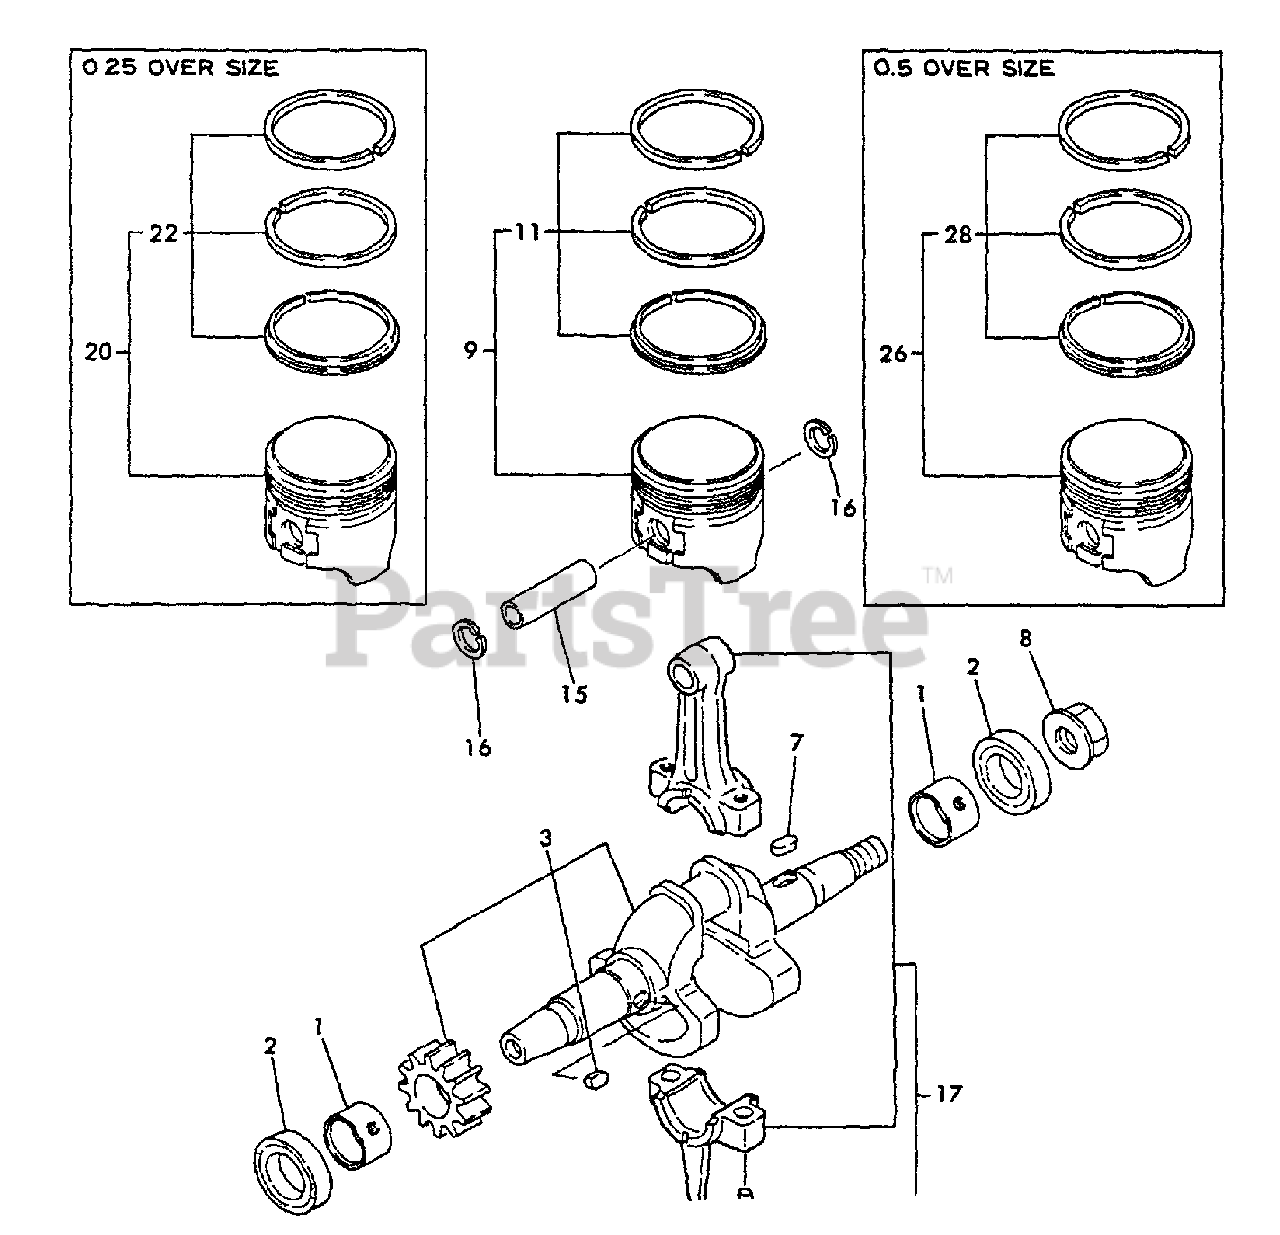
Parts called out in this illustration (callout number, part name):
1	BEARING, MAIN
2	SEAL, OIL
3	CRANKSHAFT ASSY
7	KEY - 4X10
8	NUT - 10 -- FLANGE
9	PISTON ASSY
11	PISTON RING SET
15	PIN, PISTON
16	RING, RETAINING - 11
17	CONNECTING ROD ASSY
19	BOLT, ROD
20	PISTON ASSY,O.S.= 0.25
22	RING SET O.S. = 0.25
26	PISTON ASSY,O.S.= 0.5
28	RING SET O.S. = 0.5
